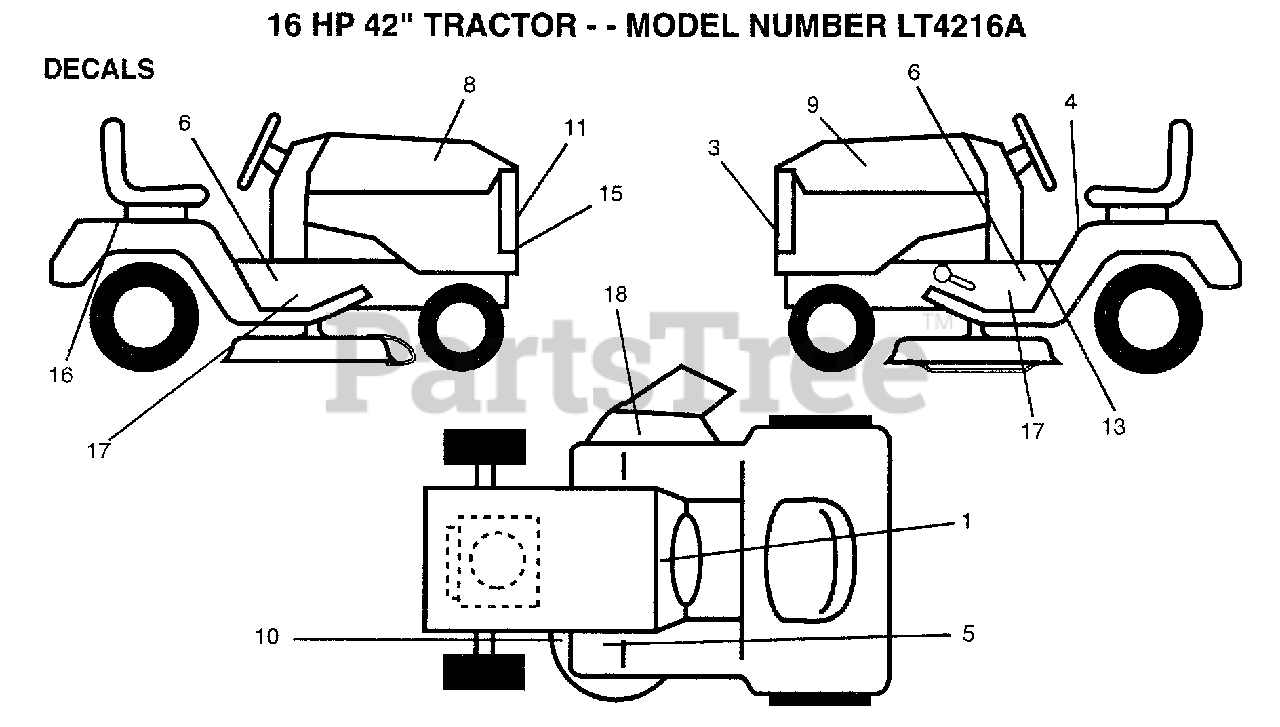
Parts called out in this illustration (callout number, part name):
1	DECAL INST OP DAS
3	DECAL LOGO GRILLE
4	DECAL CAUT FEND
5	DECAL CLUT/BRAKE
6	DECAL CHASSIS KGR
8	DECAL.HD.RH.KGRO
9	DECAL HOOD LH WIZ
10	DECAL.V.BELT
11	DECAL.GRILLE.KGRO
13	DECAL BRAK PARK
15	DECAL.GRILLE.KGRO
16	DECAL FEND QUICK
18	DECAL DANGER CT/F
